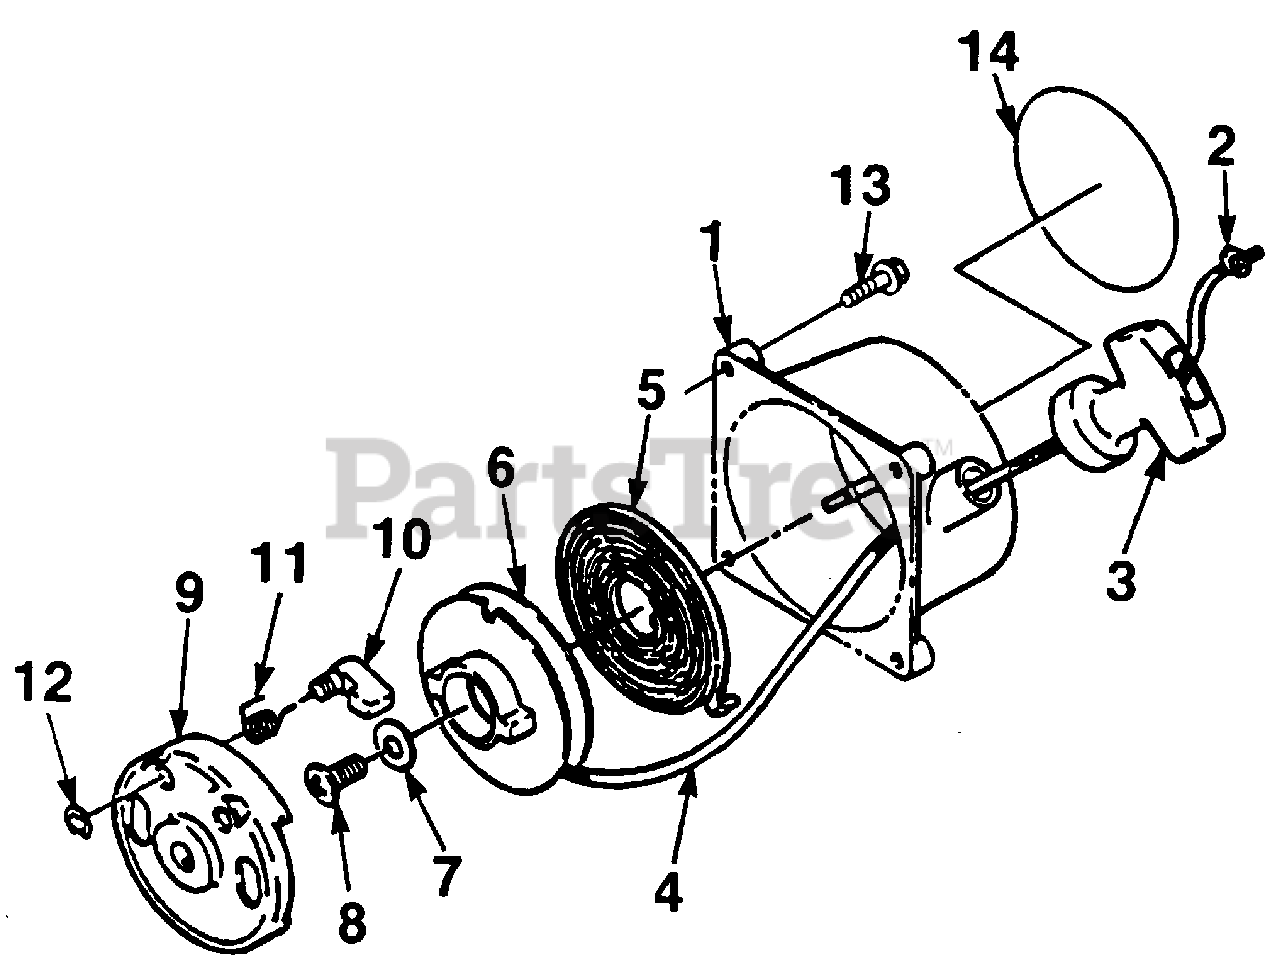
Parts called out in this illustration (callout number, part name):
1	RECOIL STARTER ASSEMBLY
3	HANDLE- Recoil starter
4	ROPE (3 x 890 MM)
5	SPRING- Spiral
6	REEL- Recoil
7	WASHER (M5)
8	SCREW (M5 x 8)
10	PAWL- Recoil
11	SPRING- Return
